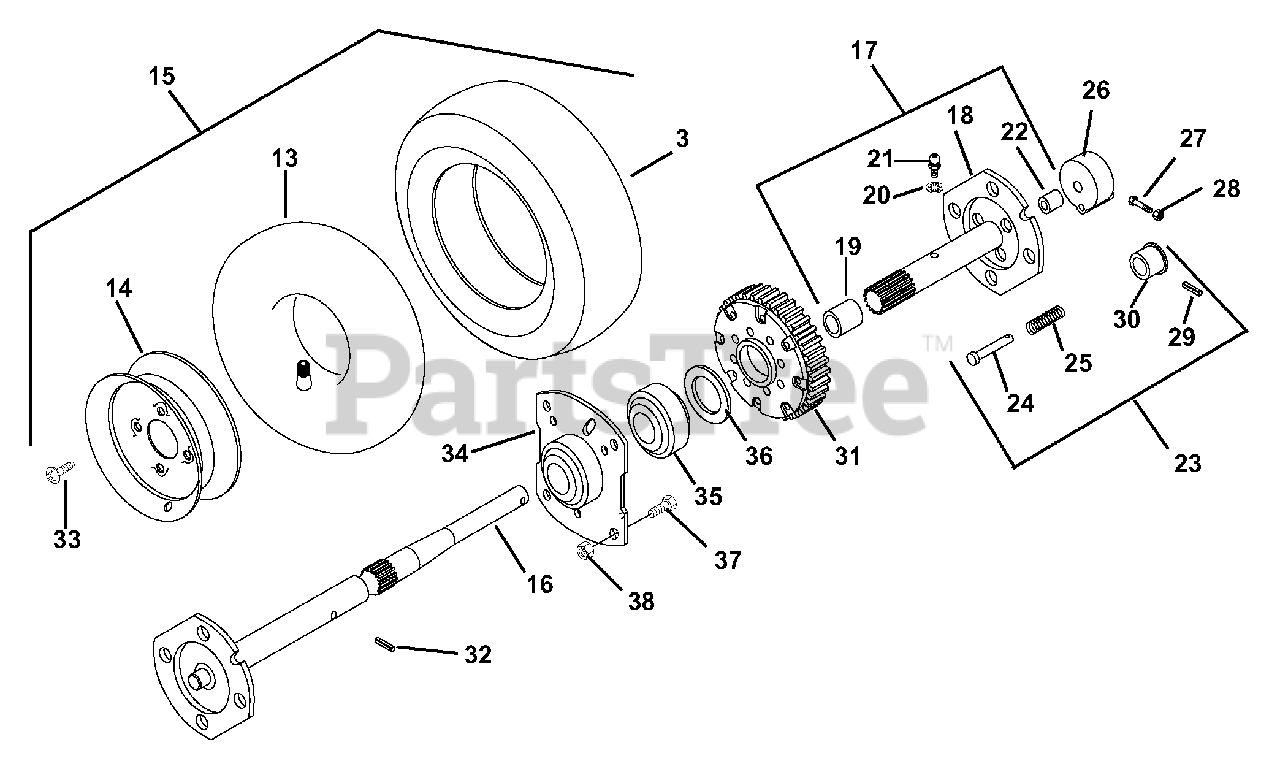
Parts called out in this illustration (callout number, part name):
3	TIRE 4.80-8 NHS
3	TIRE 16X6.50-8 SNO-HOG TREAD
13	TUBE
14	WHEEL, 4.80-8 SILVER
14	WHEEL, 6.50-8 SILVER
15	T/WHL ASSY 16X4.80-8 SNO SILVR
15	T/WHL ASSY 16X6.50-8 SNO SILVR
16	AXLE, RH
17	AXLE, LH-ASSEMBLY
18	AXLE, LH
19	BSHG-SLV .750X.814X .750 BRZ
20	WSHR-LK .250X.047 LT YWZC
21	FTG-LUBE .25-28X.256 YWZC
22	BSHG-SLV .562X.625X.625 BRZ
23	LOCKOUT HUB ASSEMBLY
24	PIN
25	SG-COMP .028X.34X1.062 WLD75
26	LOCKOUT HUB
27	BLT-HEX .25-20X2.0 PL GR8 YWZC
28	NUT-JAM-NYL .250-20 W/INSERTYZ
29	PIN-ROLL .093X1.00
30	KNOB
31	DIFFERENTIAL ASSEMBLY
32	PIN-ROLL .188X1.50
33	SCR-TAP .500-20X.62 HH YWZC
34	BEARING RETAINER
35	BRG-BALL 1.13X2.19X.63
36	WSHR-FL-STL 1.140X1.718X.134YZ
37	BLT-SERNK SL .25-20X.50 YWZC
38	@NUT-SPNLK-FLG .25-20 YWZC
